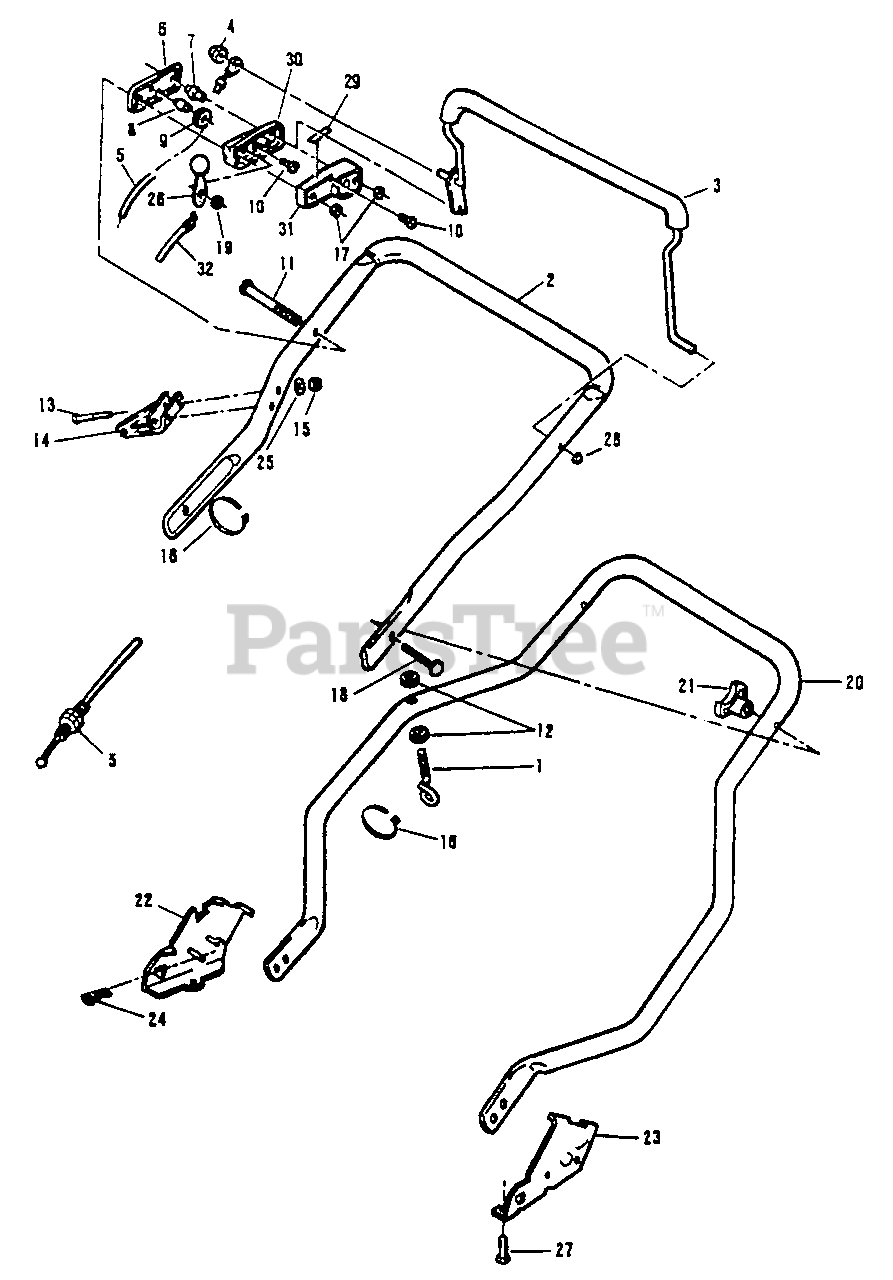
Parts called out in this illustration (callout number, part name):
1	Eye Bolt
2	Top Handle & Grip Assembly
3	Control Lever
4	Nut-Acorn
5	Control Cable Assembly
6	Control Case Outer
7	Column
8	Pin
9	Pulley
10	Screw
11	Screw
12	Lock Nut
13	Screw-Truss Head
14	Rope Guide Assembly
15	Locknut
16	Tie Strap
17	Nut-Hex-Centerlock
18	Screw-Folding Handle
19	Washer-Spring
20	Handle-Bottom
21	Knob-Folding Handle
22	Bracket-Handle-R.H.
23	Bracket-Handle-L.H.
24	Hair Pin-Handle Bracket
25	Washer
26	Lever & Knob Assembly
27	Screw-Handle Bracket to Hsg
28	Nut-Push
29	Decal-Throttle
30	Case-Throttle-Center
31	Case-Throttle-Inner
32	Throttle Cable
